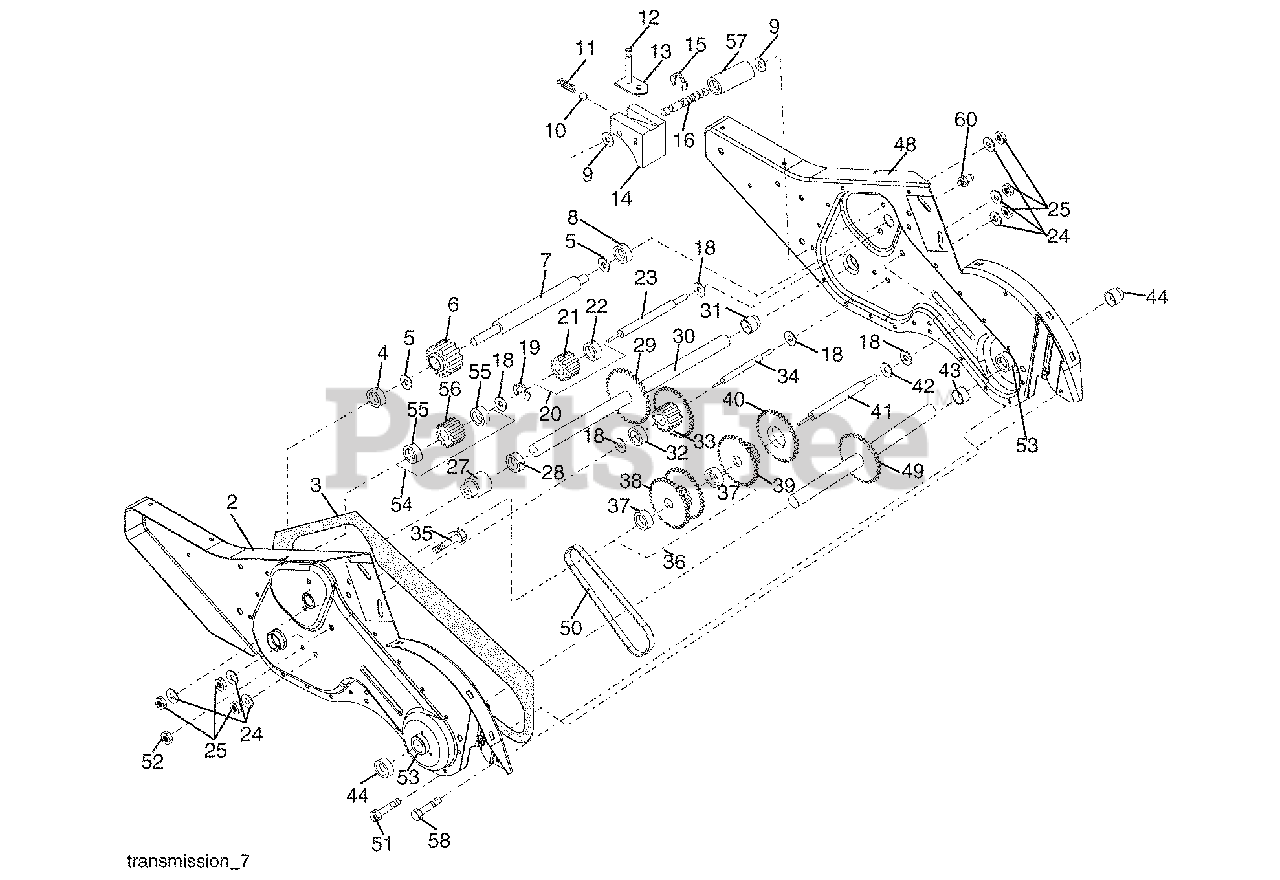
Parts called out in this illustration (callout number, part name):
1	Trans mis sion Assembly
2	Gearcase, L.H. w/Bearing
3	Gasket, Gearcase
4	Bearing, Needle
5	Washer, Thrust 5/8 x 1.10 x 1/32
6	Pinion, Input
7	Shaft, In put
8	Bearing, Needle
9	Washer, Seal
10	Ball, Steel
11	Spring, Shift, Fork
13	Arm, Shift
14	Fork, Shift
15	Ring, Klip
16	Shaft, Shift
19	Ring, Klip
20	Gear, As sem bly, Reverse Idler
21	Gear, Re verse Idler
22	Bearing, Needle
23	Shaft, Re verse Idler
24	Washer, Lock 7/16
25	Nut, Hex 7/16-20
27	Bearing, Shaft, Ground Drive L.H.
28	Spacer 0.765 x 1.125 x 1.23
29	Chain #35-50 Pitch
30	Ground Shaft Assembly
31	Bearing, Shaft, Ground Drive R.H.
32	Spacer 0.70 x 1.00 x 1.150
33	Sprocket and Gear Assembly
34	Shaft, Re duc tion (2nd)
35	Screw, Whiz, Lock 5/16-18 x 3-1/2
36	Sprocket Assembly w/Bearing
37	Bearing, Needle
38	Sprocket, Tine
39	Gear, Clus ter, Red 1st & 2nd
40	Gear, Re verse
41	Shaft, Re duc tion (1st)
42	Washer, Thrust
43	Spacer 1.01 x 1.75 x 0.760
44	Seal Asm. OIl
48	Gearcase, R.H. w/Bearing
49	Shaft, Tine
50	Chain, Roller #50-50 Pitch
51	Screw 1/4-20 x 1/2
52	Nut, Hex 5/16-18
53	Bearing Kit, Tine Shaft
54	Gear, DRT Idler w/Bearing
55	Bearing, Needle
56	Gear, DRT Idler
57	Spacer, Split .52 x .64 x 1.04
58	Screw 1/4-20 x .875
60	Fitting Grease
